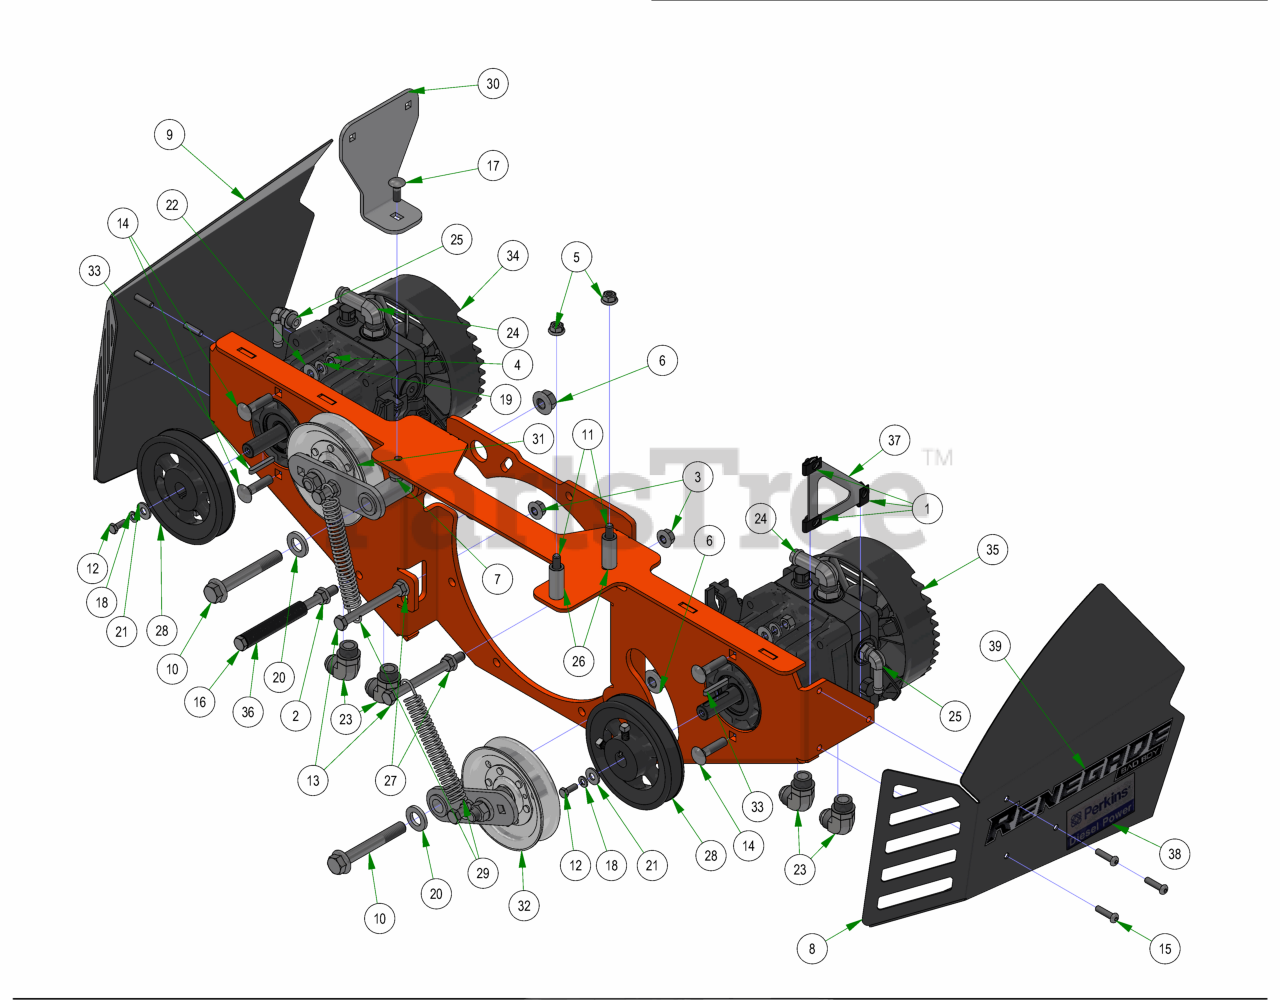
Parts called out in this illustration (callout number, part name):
1	1/4-20 Cage Nut
2	3/8-16 HEX SERRATED FLANGE NUT HARD/ZINC
3	3/8-16 NYLON INSERT FLANGE LOCKNUT (GR.F) ZINC
4	3/8-16 HEX NUT ZINC
5	5/16-18 NYLON INSERT FLANGE LOCKNUT ZINC
6	1/2-13 NYLON INSERT FLANGE LOCKNUT ZINC
7	5/16-18 HEX SERRATED FLANGE NUT HARD/ZINC
8	2019 Horizontal Pump Cover - Right - Black
9	2019 Horizontal Pump Cover - Left - Black
10	1/2-13 X 90MM HEX FLANGE BOLT W/SHOULDER (GR.8) ZINC
11	5/16-18 X 2-1/4 HEX CAP SCREW (GR.5) ZINC
12	M6-1.0 X 16MM DIN 933 HEX TAP BOLT (CL 8.8) ZINC
13	3/8-16 X 4-1/4 HEX CAP SCREW (GR.5) ZINC
14	3/8-16 X 1-1/2 CARRIAGE BOLT ZINC
15	1/4-20 x 1" BS C/S 18-8 SS
16	3/8-16 X 5-1/2 HEX CAP SCREW (GR.5) ZINC
17	5/16-18 X 7/8 CARRIAGE BOLT ZINC
18	1/4SPLIT LOCKWASHER ZINC
19	3/8 SPLIT LOCKWASHER ZINC
20	.635 ID X 1.120 OD X .140 THICK FLAT WASHER NYLON
21	1/4 USS FLAT WASHER (3/4 OD) ZINC
22	5/16 USS FLAT WASHER (7/8 OD) ZINC
23	2019 Outlaw 90 Degree Pump Fitting #6801-10-08
24	90 Degree Fitting, 1/2 x 3/4, 4601-8-8
25	90 Degree Fitting, 3/8 s 9/16
26	.380 ID X .625 OD X 1.500 LGTH 2019 OUTLAW BRAKE HANDLE SPACER ZINC
27	2020 Diesel Pump Plate Weldment - Painted
28	5" PUMP PULLEY W/ SET SCREW
29	ZT and ACS Handle Spring
30	2019 Diesel Muffler Bracket
31	2020 Diesel Pump Tensioner Assembly LH
32	2020 Diesel Pump Tensioner Assembly RH
33	5MM X 36MM SQ MACHINERY KEY C1018 ROUNDED ENDS
34	2019 Rogue/Renegade Left Pump 16cc
35	2019 Outlaw Renegade Right Pump 16cc
36	3/8 hose 4" long
37	Pump Plate Clip Nut Holder
38	PERKINS Decal
39	Renegade Back Plate Decal
